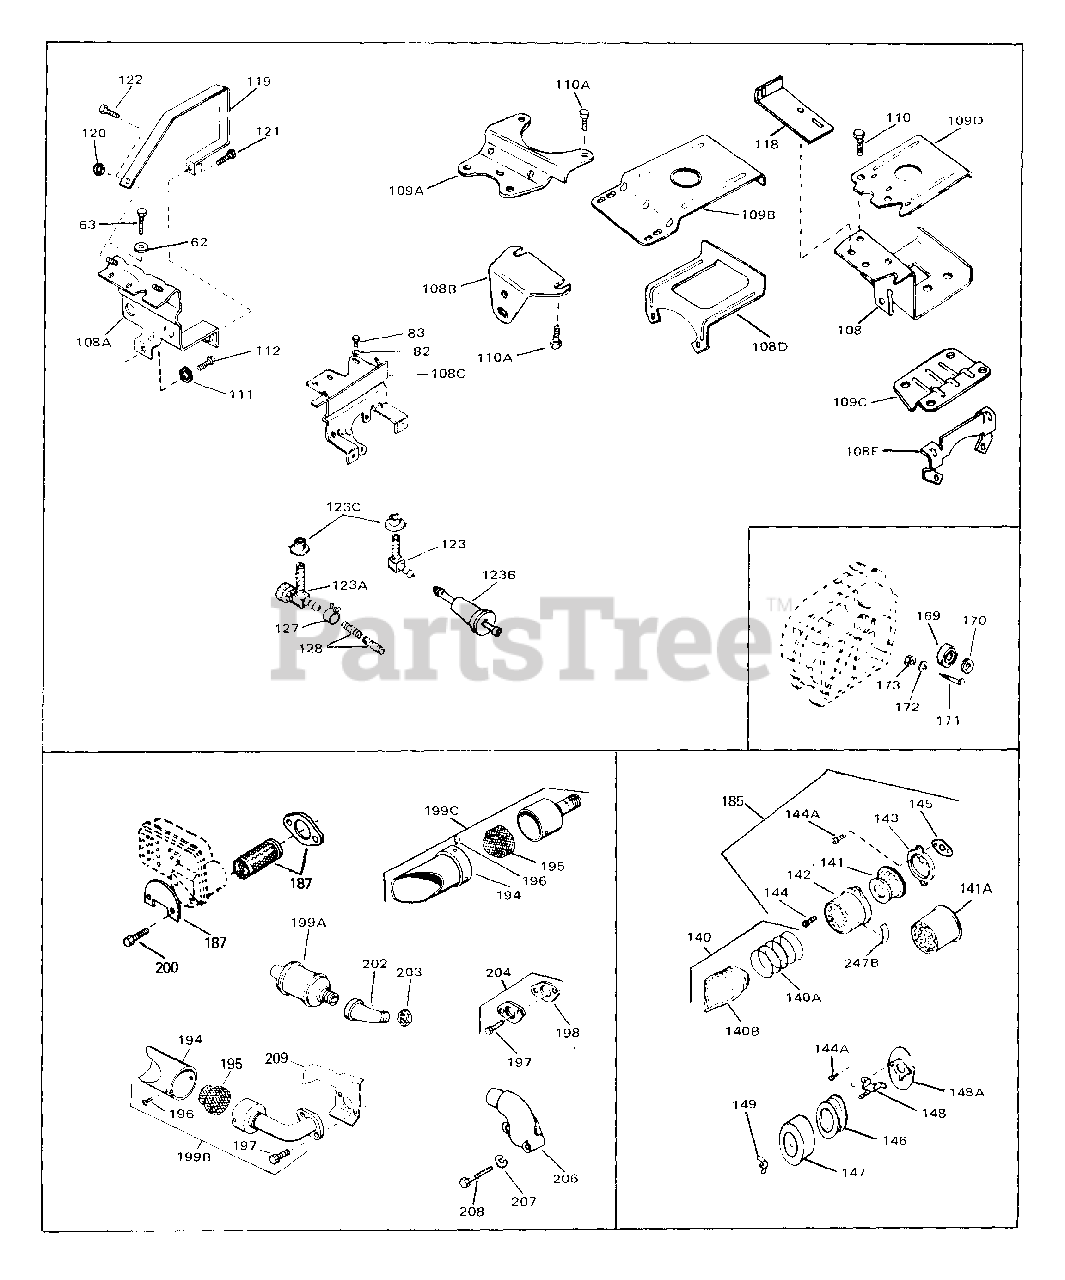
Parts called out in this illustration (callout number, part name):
62	Washer, Flat
63	Screw, Hex hd., 5/16-18 x 5/8
63	Screw, Hex hd. Sems, 5/16-18 x 7/8
82	Washer, Flat
83	Screw, Fil. hd. Sems, 5/16-18 x 1/2
83	Screw, Hex hd., 5/16-18 x 5/8
83	Screw, Hex hd. spin lock self-tap, 5/ 16-18 x
83	Screw, Hex hd., 5/16-18 x 7/8
108	Bracket, Lower fuel tank mtg.
109D	Plate, Upper fuel tank mtg.
110	Screw, Hex hd. Sems, 1/4-20 x 1/2
123A	Valve, Fuel strainer & shut-off
123C	Bushing, Fuel fitting
127	Clamp, Fuel line
128	Spring, Fuel line
185	Cleaner Assy., Air (Poly)
185	Cleaner Assy., Air (Paper)
199C	Muffler
202	Elbow, Exhaust
204	Kit, Exhaust adapter
